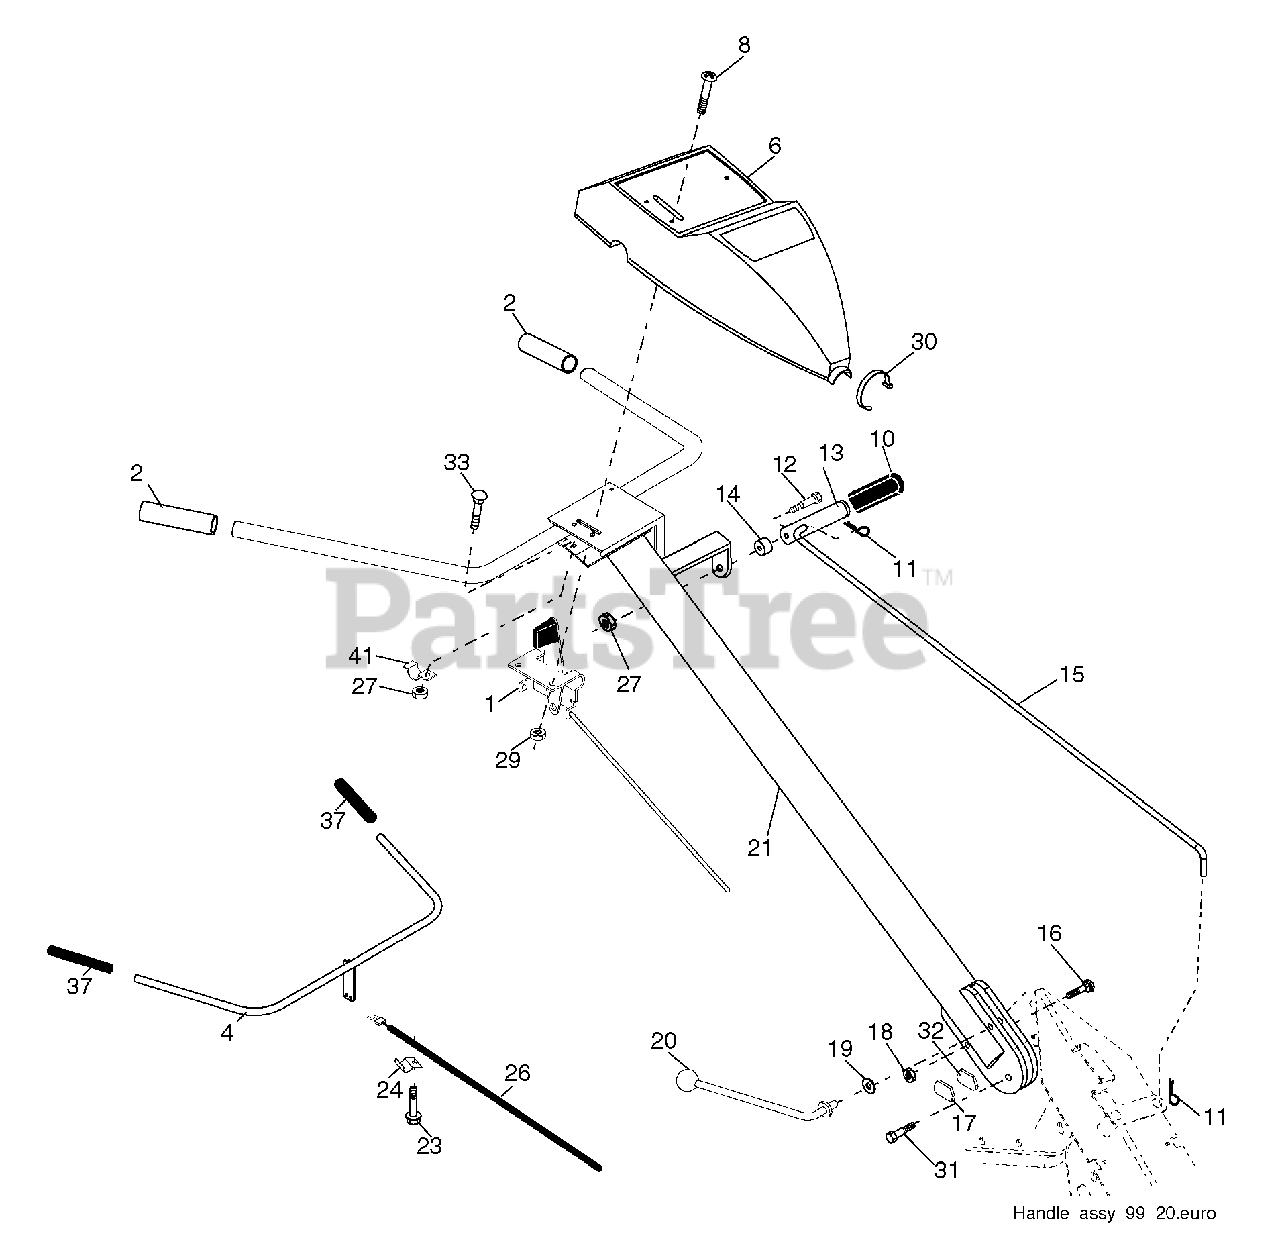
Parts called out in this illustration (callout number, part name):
1	Control, Throttle
2	Grip, Handle
4	Bar Assembly, Control
6	Panel, Control
8	Screw, Truss Hd. #10-24 unc x 1/2
10	Grip, Handle
11	Clip, Hairpin
12	Bolt, Shoulder
13	Handle, Shift
14	Grommet, Rubber
15	Rod, Shift
16	Bolt, Carriage 3/8-16 x 1 Gr. 5
17	Lock, Handle
18	Nut, Crownlock 3/8-16 unc
19	Washer 13/32 x 1 x 11 Ga.
20	Lever, Lock, Handle
21	Handle
23	Screw, Hex Washer SLT #10-24 x .50
26	Cable, Clutch
27	Nut, Hex Flange 1/4-20 unc
29	Nut, Keps #10-24 unc
30	Tie, Cable
31	Bolt, Pivot
32	Lock, Handle
33	Bolt, Carriage 1/4-20 unc x 1/2
37	Grip, Bar, Control
41	Clamp, Bar, Control
